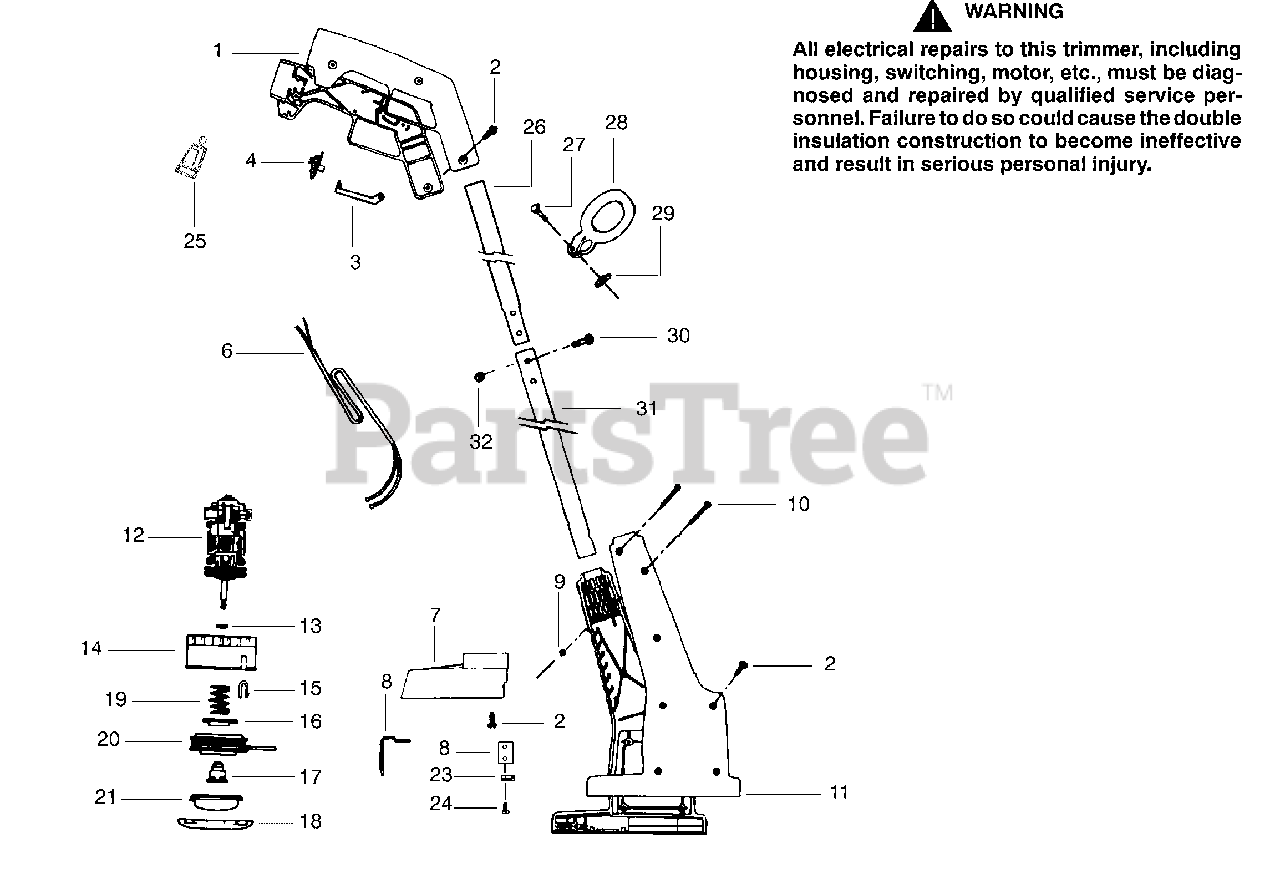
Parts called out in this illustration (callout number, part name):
1	Upper Handle Set
4	On/Off Switch
6	Wiring Harness
7	Shield 1210-T2 & T3
7	Shield 1212-T1, T2 & T3
8	Line Limiter 1210-T1
8	Line Limiter 1210-T2, T3, & 1212-T1, T2 & T3
11	Motor Hsg. Set 1210-T3 &1212-T1, T2, T3
12	Motor Assembly 1210-T1 & T2
12	Motor Assembly 1212-T1 & T2
12	Motor Assembly 1210-T3
12	Motor Assembly 1212-T3
15	Line Saver
16	Spring Cap
17	Drive Gear Ass'y.
20	Spool w/Line
21	Release Button
23	Blade Cover 1210-T2 & T3
23	Blade Cover 1212-T1, T2 & T3
24	Screw 1210-T2 & T3
24	Screw 1212-T1, T2 & T3
25	Cord Retainer
26	Upper Tube
28	Assist Handle
29	Wing Nut
31	Lower Tube Assy.
32	Nut
